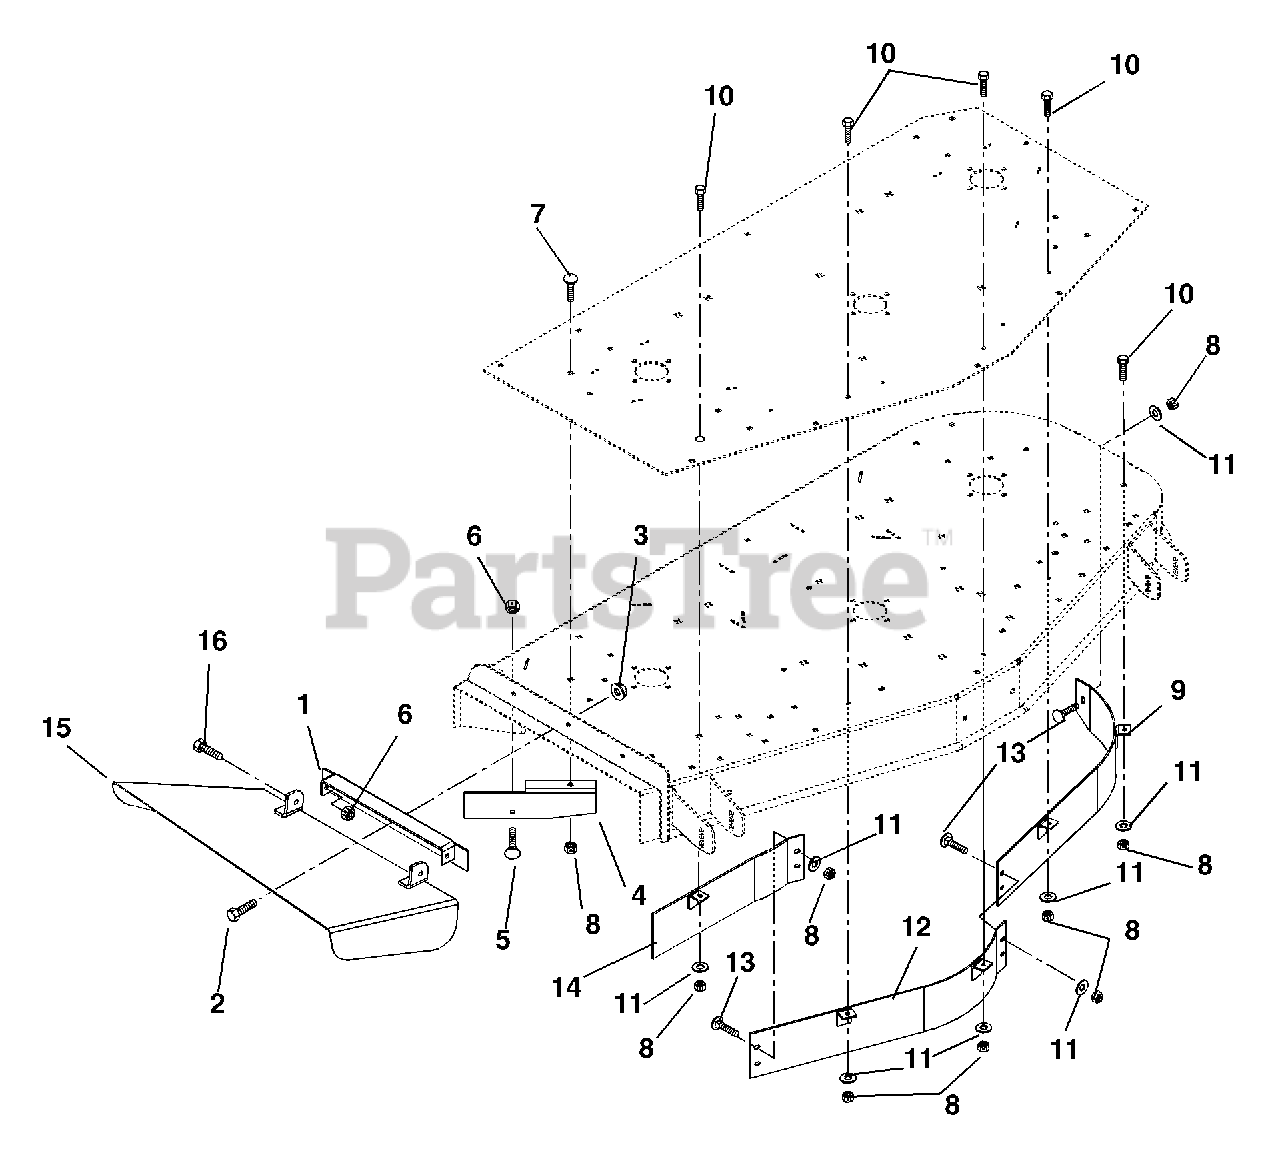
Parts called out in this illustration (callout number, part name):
1	Weldment, Discharge Chute Bracket
2	Bolt-Hex .38-16 x 1.00 Grade 5
3	Nut-Locking-Flange .38-16
4	Deflector, 60
5	Bolt-Round Head Square Neck .38-16 x 1.00 Grade 2
6	Nut-Locking-Center .38-16
7	Bolt-Round Head Square Neck .31-18 x 1.00 Grade 5
8	Nut-Locking-Nylon .31-18
9	Weldment, 60" Left Hand Baffle-Upper
10	Bolt-Hex .31-18 x 1.00 Grade 5
11	Washer-Flat-Steel .312 x .734 x .065
12	Weldment, 60" Center Baffle-Up
13	Bolt-Round Head Square Neck .31-18 x .75 Grade 5
14	Weldment, 60" Right Hand Baffle-Upper
15	Weldment, Discharge Chute 60"
16	Bolt-Hex .38-16 x 1.00 Grade 5
17	60" Discharge Cover
18	60" Mulch Kit
